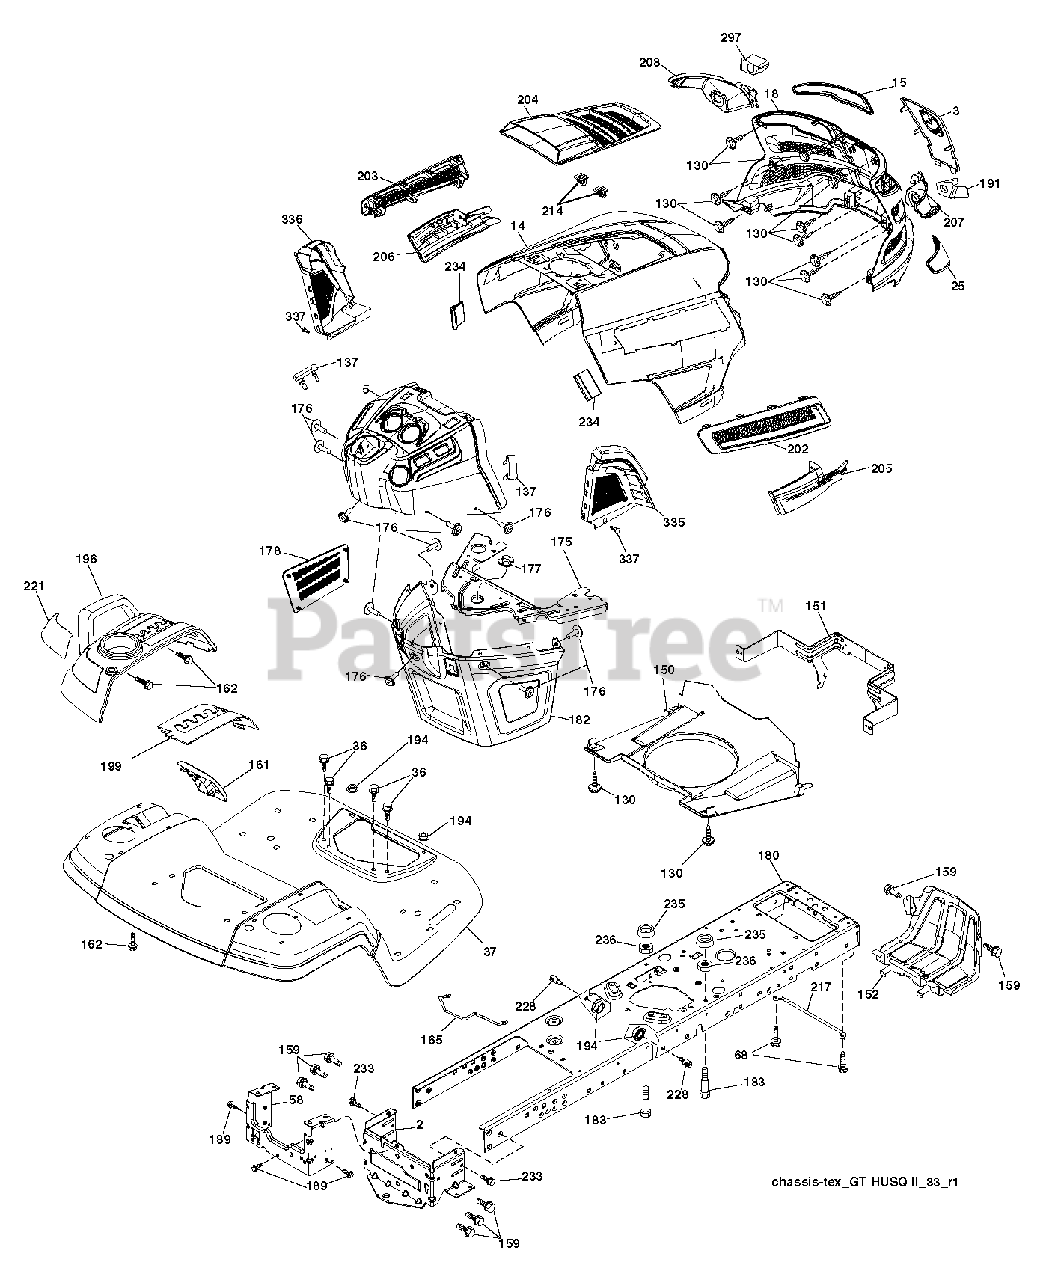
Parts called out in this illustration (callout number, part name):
2	DRAWBAR.LOWER.2PC.18/22
3	APPLIQUE.SUBASM.GT.HUSQ.II
5	DASH.UPP.GT2.DUAL.RD.PTO.MCHOK
14	HOOD.ASM.HUSQVARNA.GT.TEX.ORAN
15	LENS.HEADLIGHT.LH.GTII.2011
18	GRILLE.SUBASM.GT.HUSQ.II
25	LENS.HEADLIGHT.RH.GTII.2011
36	SCREW 5/16"
37	FENDER.PNT.TX.GT.CH/FW/DL.HUSQ
58	DRAWBAR.UPPER.2PC,LRG.FENDER
68	SCREW LT
130	SCREW.#10 X 0.750.BOS
137	BUMPER DASH
150	AIR.DUCT.GTV.BLACK
151	BRACKET.PIVOT.HOOD.GT.HUSQ.II
152	SHIELD.BROWNING.PNT.GT.V2
159	SCREW, 3/8-16X3/4
161	CONSOLE.WINDOW.FUEL.HUSQ.GT
162	SCREW.HI-LO.CONSOLE
165	SUPPORT.TANK.REAR.B/TE
175	PLATE.CROSSMEMBER.HUSQ
176	SCREW.#10-24X5/8.RN.QU
177	BUSHING, STEERING
178	CARGO.ASM.NET.TXGT.W/C
180	CHASSIS.STAMPING.LT/GT
182	DASH.LOWER.COMMON.12V.ADAPTOR
183	BOLT.5/16-18X1-1/4 FULL THD
189	SCREW
191	INSERT.REFLECTIVE.RH.HUSQ.GTII
194	NUT LOCK HEX FLANGE 5/16-18
196	CONSOLE.ASM.DECKLIFT.HUSQGT.DL
199	PLATE.DECK.LIFT.HUSQVARNA.GT
202	VENT.SIDE.RH.GT.HUSQ.II.
203	VENT.SIDE.LH.GT.HUSQ.II.498
204	VENT.TOP.HUSQ.GT2
205	SIDE.TRIM.RH.GT.HUSQ.II
206	SIDE.TRIM.LH.GT.HUSQ.II.GRAY
207	BEZEL LIGHT.RH.GT.II.MYLAR
208	BEZEL LIGHT.LH.GT.II.MYLAR
214	CLIP.RETAINER.TINNER.
217	ROD.PIVOT.HOOD
221	REFLECTOR.LH.TEX GT HU
228	STUD.FASTNER.W/ANTI-ROTATE
233	BOLT.SHOULDER
234	BUMPER.HOOD.TEX.HUSQVARNA
235	SPACER FENDER
236	NUT.CENTERLOCK.5/16-
297	INSERT.REFLECTIVE.LH.HUSQ.GTII
335	COVER.RH.CLOSE.OUT.BLACK
336	COVER.LH.CLOSE.OUT
337	CLIP.XMAS.TREE.ITW.2622-00
